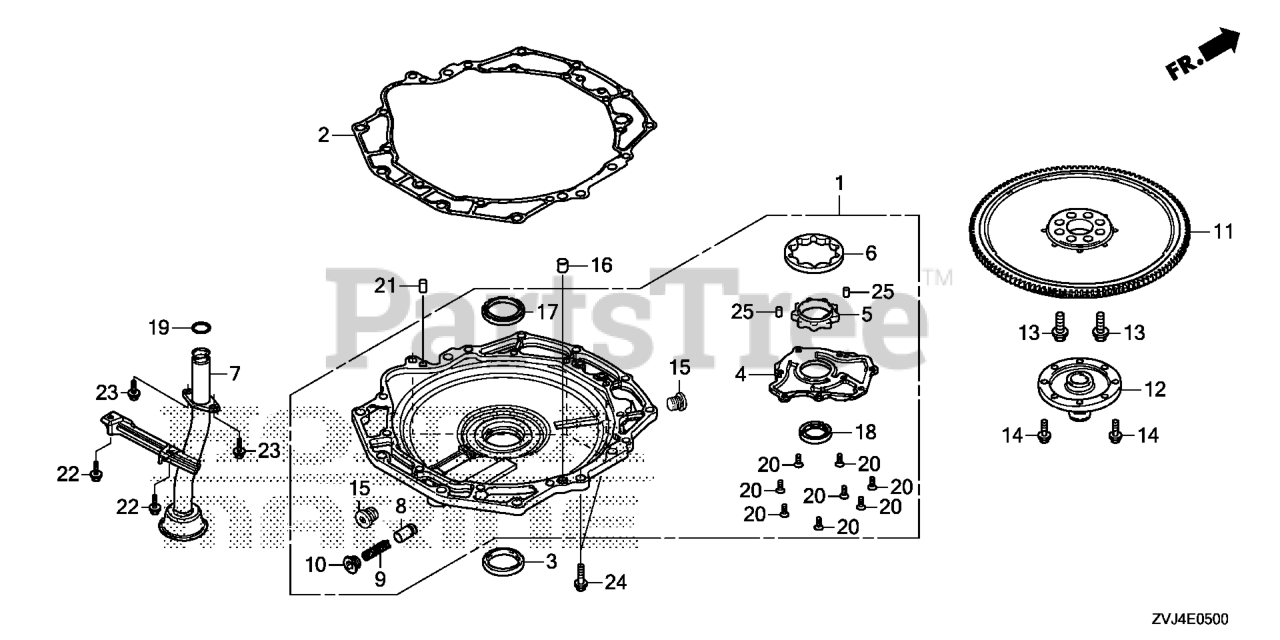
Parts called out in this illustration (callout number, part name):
1	PUMP ASSY., OIL *NH8* (DARK GRAY)
1	PUMP, OIL *NH8*
2	GASKET, OIL PUMP BODY
3	RUBBER, OIL PUMP
4	COVER, OIL PUMP
5	ROTOR, OIL PUMP (INNER)
6	ROTOR, OIL PUMP (OUTER)
7	STRAINER, OIL
8	VALVE, RELIEF
9	SPRING, RELIEF VALVE
10	BOLT, SEALING (18MM)
11	FLYWHEEL *TBLACK* (BLACK)
12	BOSS, FLYWHEEL
13	BOLT (12MM)
14	BOLT, SPECIAL (8MM)
15	BOLT, SEALING (22MM) (NOT AVAILABLE)
15	BOLT, SEALING (22MM)
16	PIN, DOWEL (14X15)
17	OIL SEAL (46X60X9)
18	OIL SEAL (31X46X7) (NOK)
19	O-RING (20.6X2.6)
20	SCREW, FLAT (6X16) (YAMADA)
21	PIN B, DOWEL (10X16)
22	BOLT, FLANGE (6X14)
23	BOLT, FLANGE (6X18)
24	BOLT, FLANGE (8X30)
25	ROLLER (5X8)
